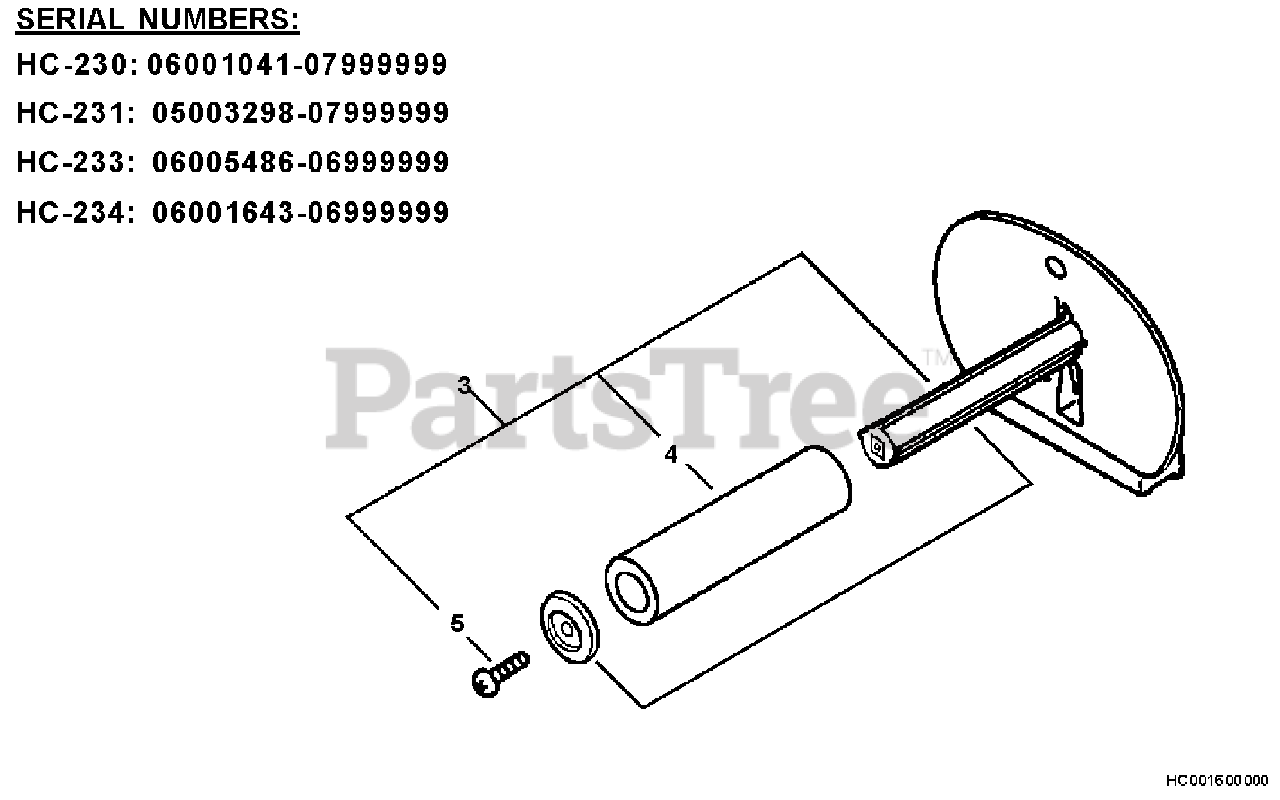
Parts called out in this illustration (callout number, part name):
3	HANDLE ASSY - FRONT
4	GRIP, HANDLE
5	SCREW - 5X14
